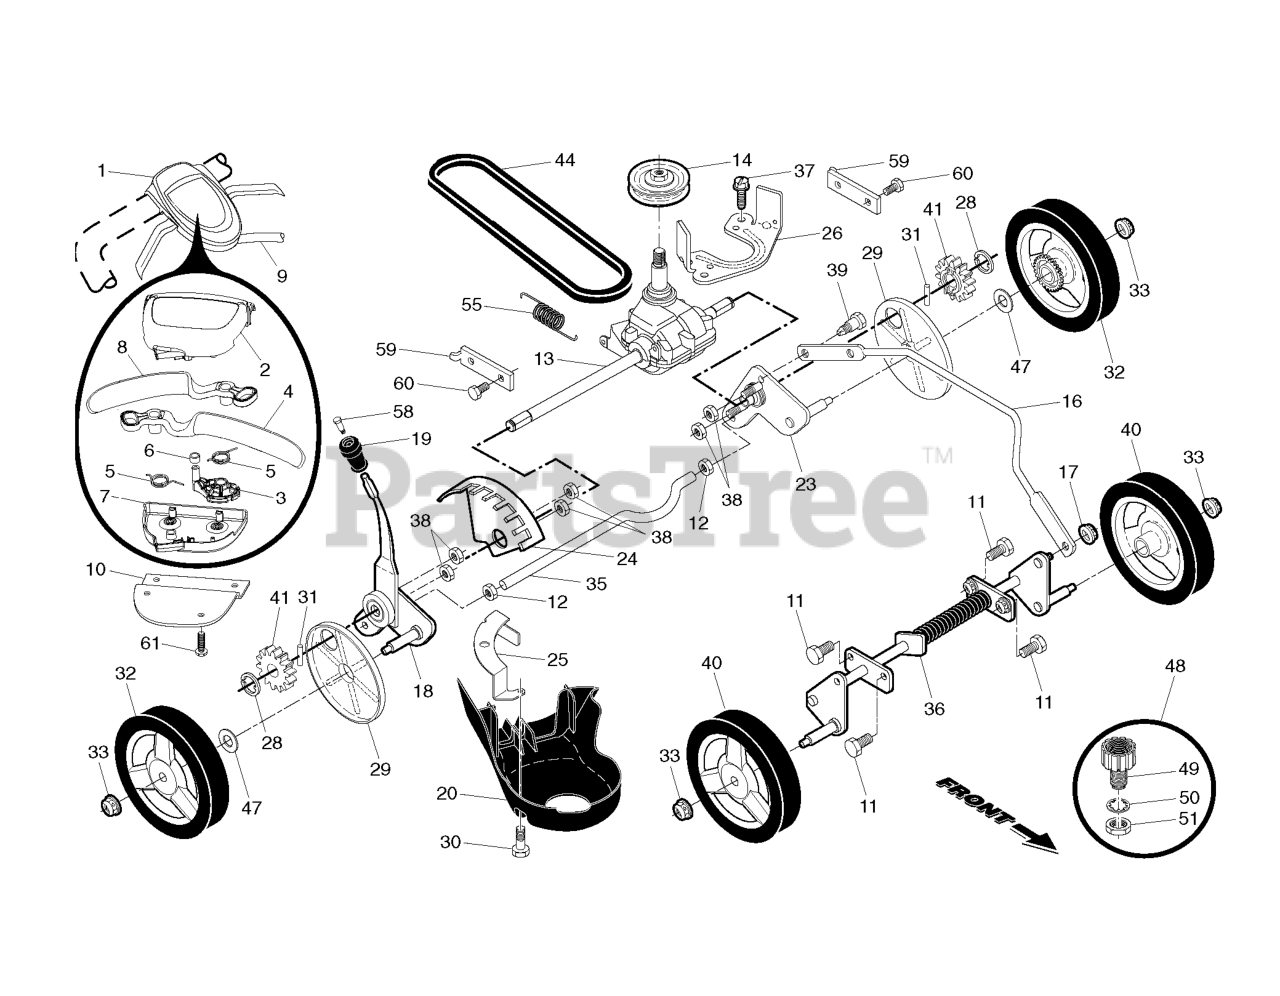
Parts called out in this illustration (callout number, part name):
1	RB CTRL.AW2.22+RGD.BS.GRY/BLK
2	RP CASE.CONT.ROL.TOP.HUSQV.
3	CAM.GEN2.DUAL.TRIGGER
4	LEVER.CONTROL.LH.22+.CURVE.BLA
5	SPRING, DRIVE CONTROL
6	BUSHING.CONTROL.CAM
7	COVER.DR.CONTROL.LOWER.GRAY
8	LEVER.CONTROL.RH.22+.CURV.BLAC
9	CABLE.CONTROL.22RGD.GEN2
10	BRACKET.DRIVE.CONTR.GEN2.BLACK
13	TRANMISSION.22+.RGD.AW
16	ROD.CONNECTING.RGD.22+.HW.BLAC
17	NUT.LOCK.5/16-18
18	SELECTOR.ASM.22+.RT.SPT LW RGD
19	KNOB.SEL.SPRING.22+.SP.RIB.BLK
20	COVER.BELT.22.RGD
23	Wheel Axle Assembly, LH
24	BRACKET.WHL.ADJ.9.POS.W/PAD
25	BRACKET.DRIVE.COVER.RGD.BZP
26	BRACKET.TRANS.BELT.KEEPER.BZP
28	E-RING 7/16 RE
29	COVER.DUST.WHEEL
30	BOLT.HEX.HD.WASHER.5/16-18X.75
31	PAWL, DRIVE
32	WHEEL & TIRE ASSY, REAR
33	NUT.HEX.FLANGE.3/8-16.LO(3 2)
35	AXLE.REAR.RGD
36	AXLE.ASM.FRONT.RGD.BZP
38	NUT.HEX.FLANGE.1/4
39	SHOULDER BOLT SEMI GIMLET PT.
40	WHEEL & TIRES ASSY, FRONT
41	PINIION.14.TOOTH.RGD
44	BELT.DRIVE.RGD.PLUS
47	WASHER FLUT
48	KIT.WASH-OUT.PORT
49	FITTING, HOSE, WATER WASHOUT
50	WASHER.LOCK.INTERNAL.TOOTH
51	LOCKNUT.HEX.WITH.O-RING
58	BOLT.HEX.HD.WASHER.5/16-18X.75
59	BRACKET.SUPPORT.22+.RWGD.BZP
60	BOLT.HEX.HD.WASHER.5/16-18X.75
61	SCREW, PHILLIPS HEAD 10 X 5/8
